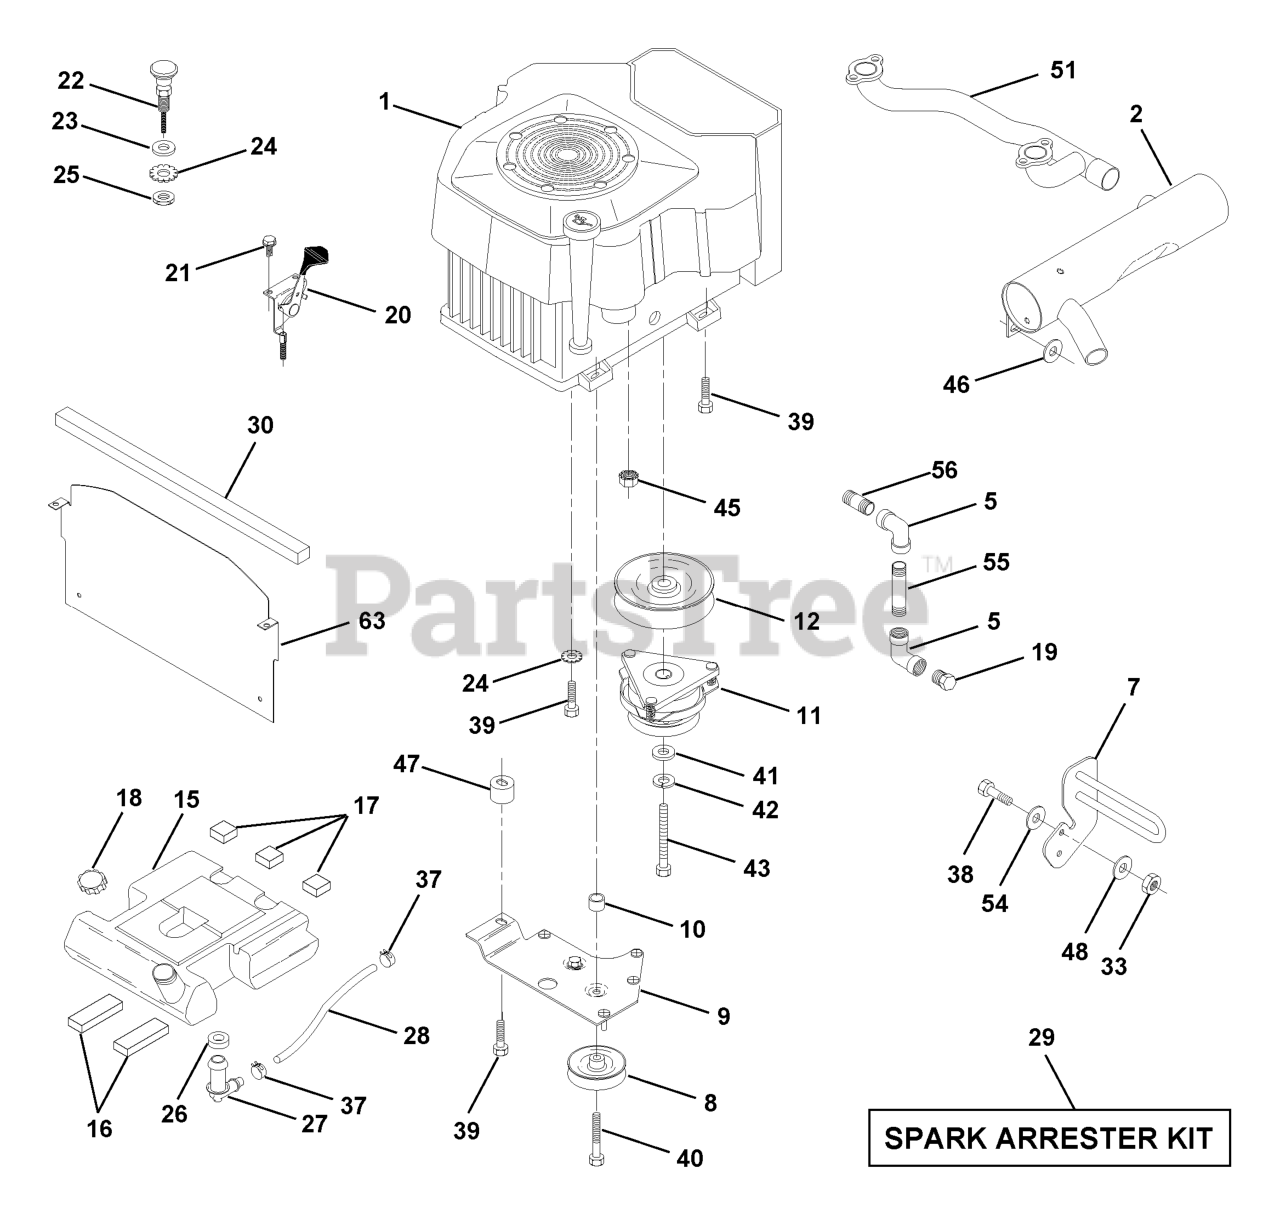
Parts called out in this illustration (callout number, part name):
2	MUFFLER VGT CYLINDER
5	ELBOW
7	MUFFLER GUARD
8	RP.IDLER GROOVED
9	BELT KEEPER
11	CLUTCH ELECTRIC
12	PULLEY ENG VGT ELECT CLUTCH
15	FUEL TANK REAR YT/GT
16	PAD IDLER TI
17	PAD-SPACER LT
18	FUEL CAP
19	PLUG T
20	THROTTLE CONTROL
21	SCREW LT
22	CHOKE CONTROL
23	WASHER
24	LOCKWASHER
25	NUT
26	BUSHING OUTLET T
27	STEM FUEL TANK
28	HOSE
29	SPARK ARRESTOR
30	FOAM-STRIP LT
33	NUT
37	HOSE CLAMP
38	BOLT
39	SCREW TT 3/8-16X2-1/4 UNC
40	Screw TT 3/8-16 x 4 UNC
42	LOCKWASHER
43	BOLT HEX
45	NUT FLANGE 1/4-20 STARTER NUT
46	WASHER
47	SPACER.ENGINE.CV22.ROUND.PM
48	Washer 13/32 x 1-1/4 x 7 Ga.
51	PIPE CROSSOVER
55	NIPPLE, PIPE 3/8NPT X 4-1/2
56	NIPPLE, PIPE 3/8 NPTX1.00
63	SHIELD, HEAT VGT YP/HUSQ
